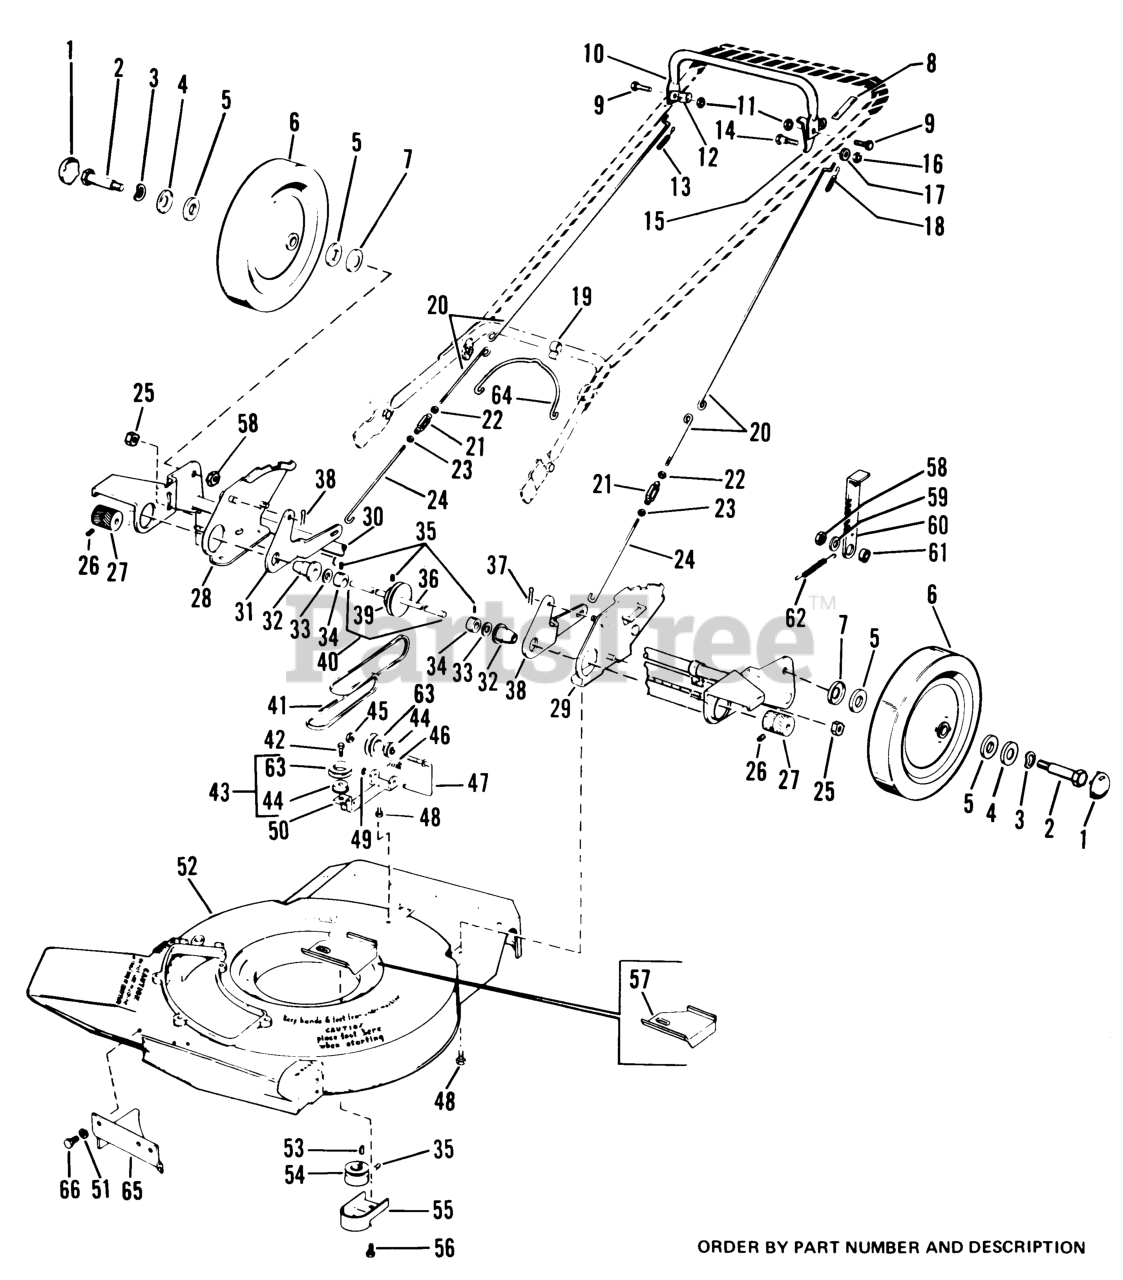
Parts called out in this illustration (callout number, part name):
2	BOLT, Rear Wheel
3	WASHER, Spring
4	HOUSING, Seal
5	SEAL, Housing (Mfg. No. 1690132 Only)
5	SEAL, Housing
6	WHEEL, 10" Rear
7	HOUSING, Seal
8	FILM, Handle
9	BOLT, Shoulder, Handle
10	HANDLE (Assy. 1653231)
11	LOCKNUT, Full Hex, Jam, 5/16-18
12	ANCHOR, Engaging Rod, R.H. (Assy. 1653231)
13	SPRING, Rod Ret. R.H.
14	STOP, handle
15	ANCHOR, Engaging rod, L.H. (Assy 1653231)
16	LOCKNUT, Flange, 5/16-18
17	WASHER, Plain, 1/4
18	SPRING, Rod ret. L.H.
20	ROD, Engaging Upper
22	NUT, Full Hex, No. 10-24, L.H. Thread
23	NUT, Hex Full, No. 10-24
24	ROD, Engaging Lower
25	LOCKNUT, Flange, 5/16-18
26	SETSCREW, 5/16-18 x 1/4
27	DRIVER, Wheel
28	BRACKET ASSY, R.H.
29	BRACKET ASSY, L.H.
30	PLATE & TUBE ASSY, Manual 176116 E.S.
31	BELLCRANK, R.H.
32	BEARING & RETAINER ASSY
33	SEAL, Grease
34	COLLAR, Set
35	SETSCREW, 5/16-18 x 1/4
36	SHAFT, Drive Wheel
37	PIN, Cotter, 3/32 x 5/8
38	BELLCRANK, L.H.
39	PULLEY, Drive
40	SHAFT & PULLEY ASSY
41	BELT, Drive
42	SCREW, Thd. Forming, 1/4-20 x 1
43	PULLEY ASSY, Idler
44	BEARING, Idler
45	LOCKNUT, Flange, 1/4-20
46	SPRING, Torsion, Idler
47	U-BOLT, Idler
48	SCREW, Thd. Forming, 1/4-20 x 3/8
49	RING, "E" Type
50	BRACKET, Idler Support
51	LOCKWASHER, 1/4
52	HOUSING, 21"
53	KEY, Woodruff, #5, 1/8 x 5/8
54	PULLEY, Engine
55	COVER, Drive Lower
56	SCREW, Cover #12-24 x 1/2
57	DEFLECTOR, Oil
58	LOCKNUT, Full Hex, 3/8-16
59	WASHER, Plain, 5/16
60	ADJUSTER, Height Rear
61	SPACER, Height Adj.
62	SPRING, Height Adj.
63	PULLEY, Idler
64	SPRING, Rod
65	GUARD ASSY, Stone
66	CAPSCREW, Hex 1/4-20 x 1/2
